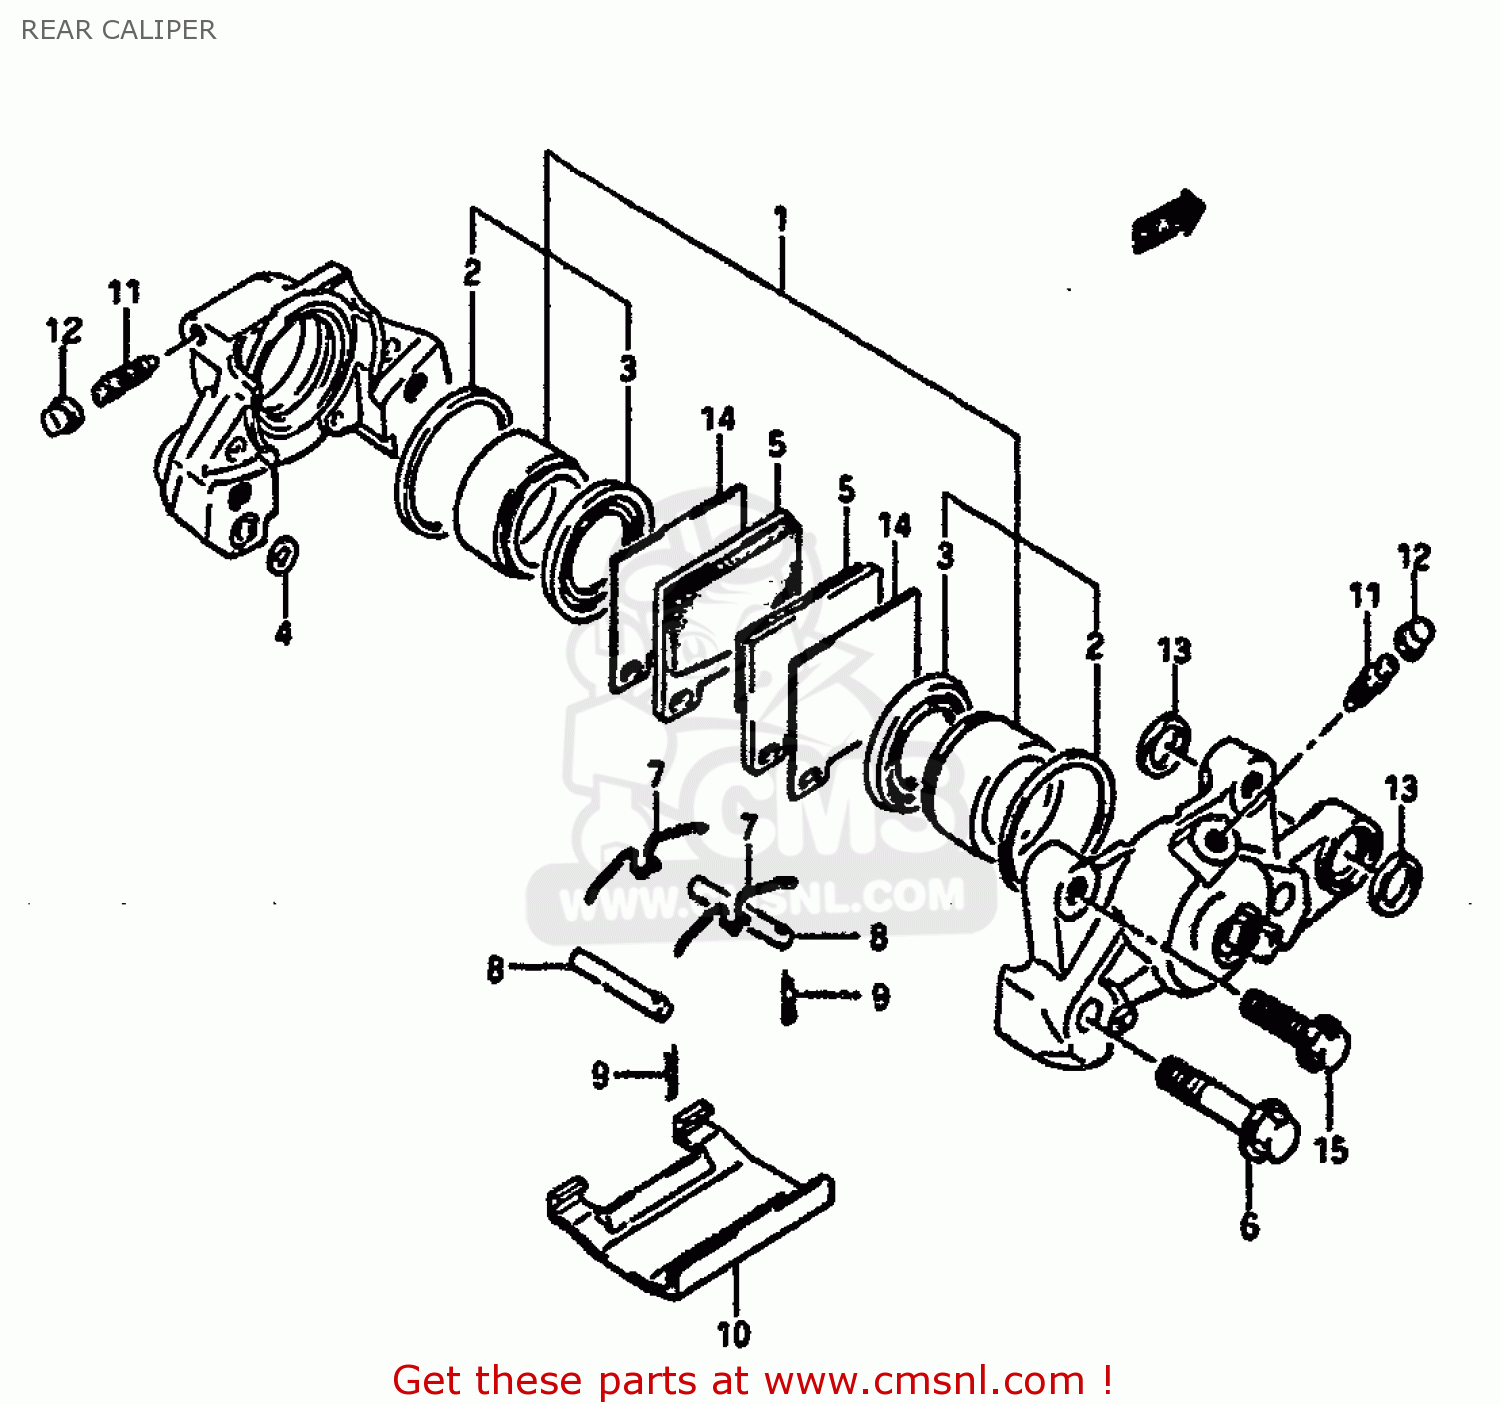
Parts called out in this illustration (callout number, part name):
1	PISTON SET
2	SEAL,PISTON
3	BOOT
4	SEAL,JOINT
5	PAD,BRAKE
6	BOLT,HOUSING
7	SPRING
8	PIN,PAD
9	CLIP,PAD PIN
10	COVER
11	BLEEDER
12	CAP,BREATHER
13	SEAL,RR CUSHION ROD LWR
14	SHIM,PAD
15	BOLT
